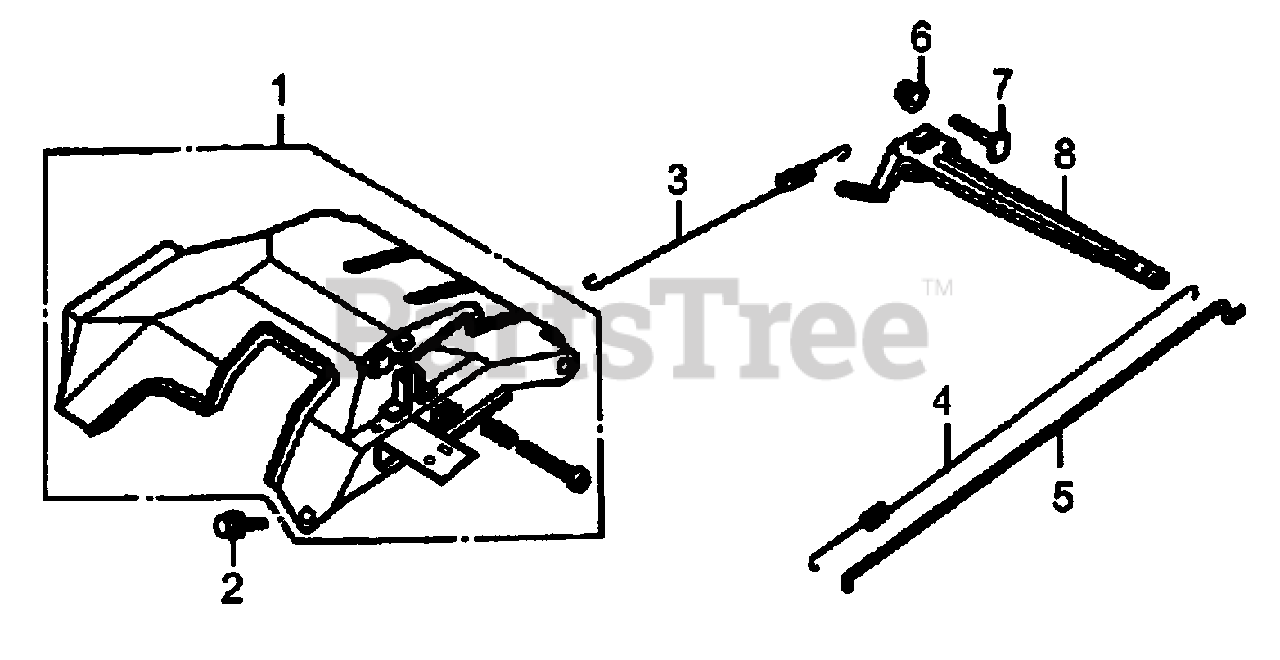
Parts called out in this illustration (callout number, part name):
1	BRACKET HOUSING ASSY.
2	BOLT, FLANGE 6X12
3	SPRING, GOVERNOR A
4	SPRING, ANTI-LASH
5	ROD, GOVERNOR
6	NUT, FLANGE, M6
7	BOLT, GOVERNOR ARM
8	ARM, GOVERNOR
